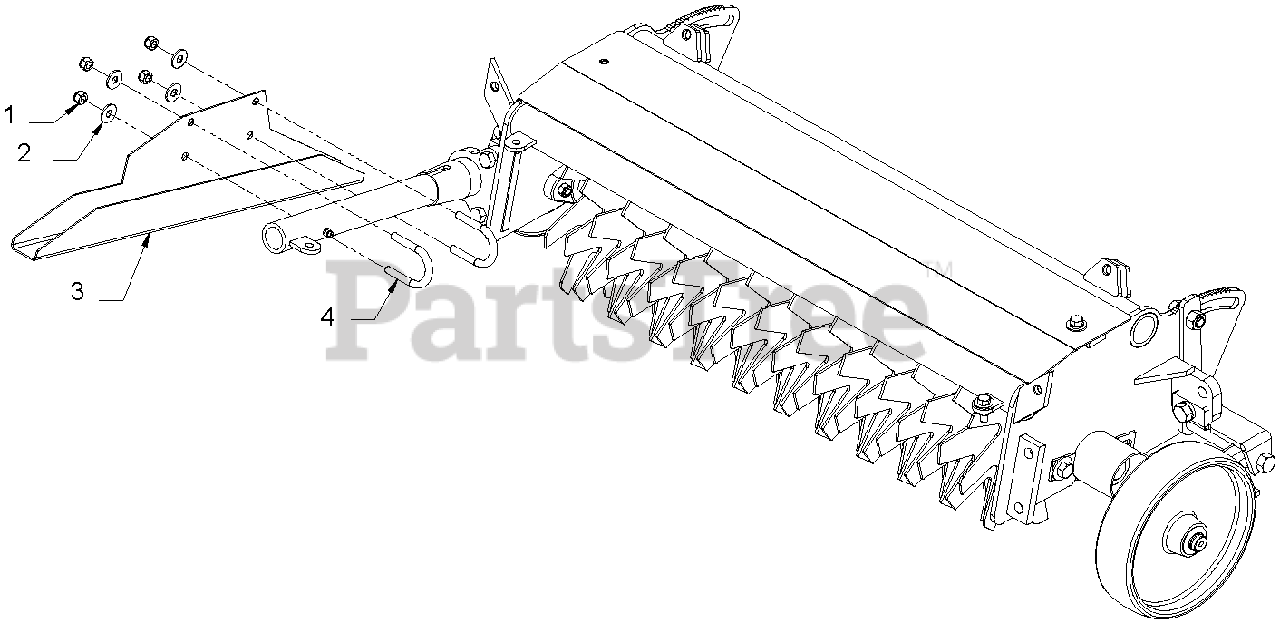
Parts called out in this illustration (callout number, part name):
1	Nut, Hex 5/16-18 Nyloc CP
2	Washer, Flat 5/16 SAE Hard YZ
3	Guard, Spring, Verticutter
4	U-Bolt, 5/16-18 x 1-3/8 x 2-3/16
